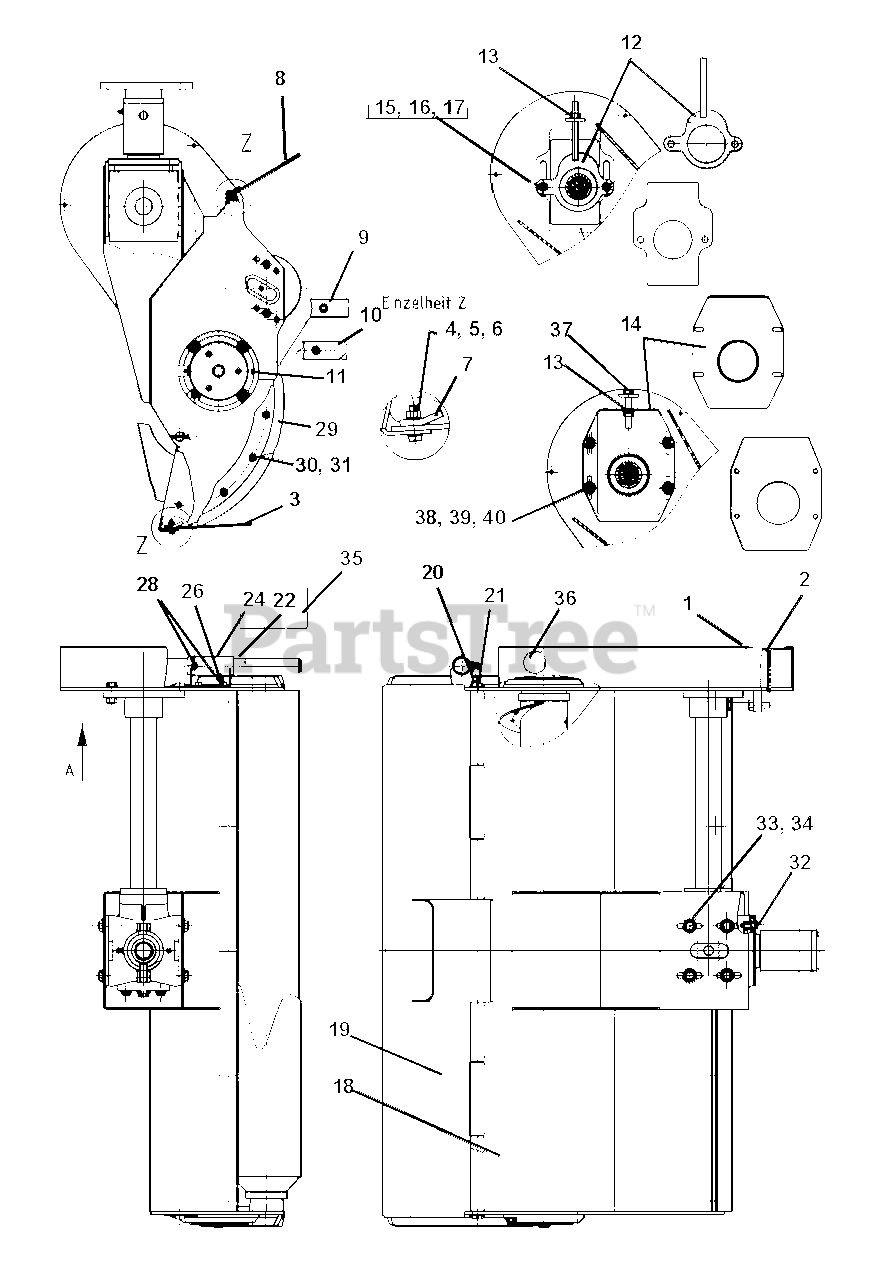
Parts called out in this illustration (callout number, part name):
1	Cover, V-Belt
2	Bolt, Hex Head
3	Protection Front
4	Bolt, Hex Head
5	Nut, Hex
8	Protection Rear
9	Plate, Metal
10	Plate, Metal
11	Screw, Flat Head
13	Nut, Hex
15	Bolt, Hex Head
16	Nut, Hex
20	Pin, Hinge
22	Leg, Supporting
23	Leg, Supporting
26	Bolt, Hex Head
27	Bolt, Hex Head
29	Skid, Landing
30	Screw, Flat Head
31	Nut, Self Locking Hex
32	Bolt, Hex Head
33	Bolt, Hex Head
35	Leg, Supporting
36	Cover, Plastic
37	Bolt, Hex Head
38	Bolt, Hex Head
40	Nut, Self Locking Hex
